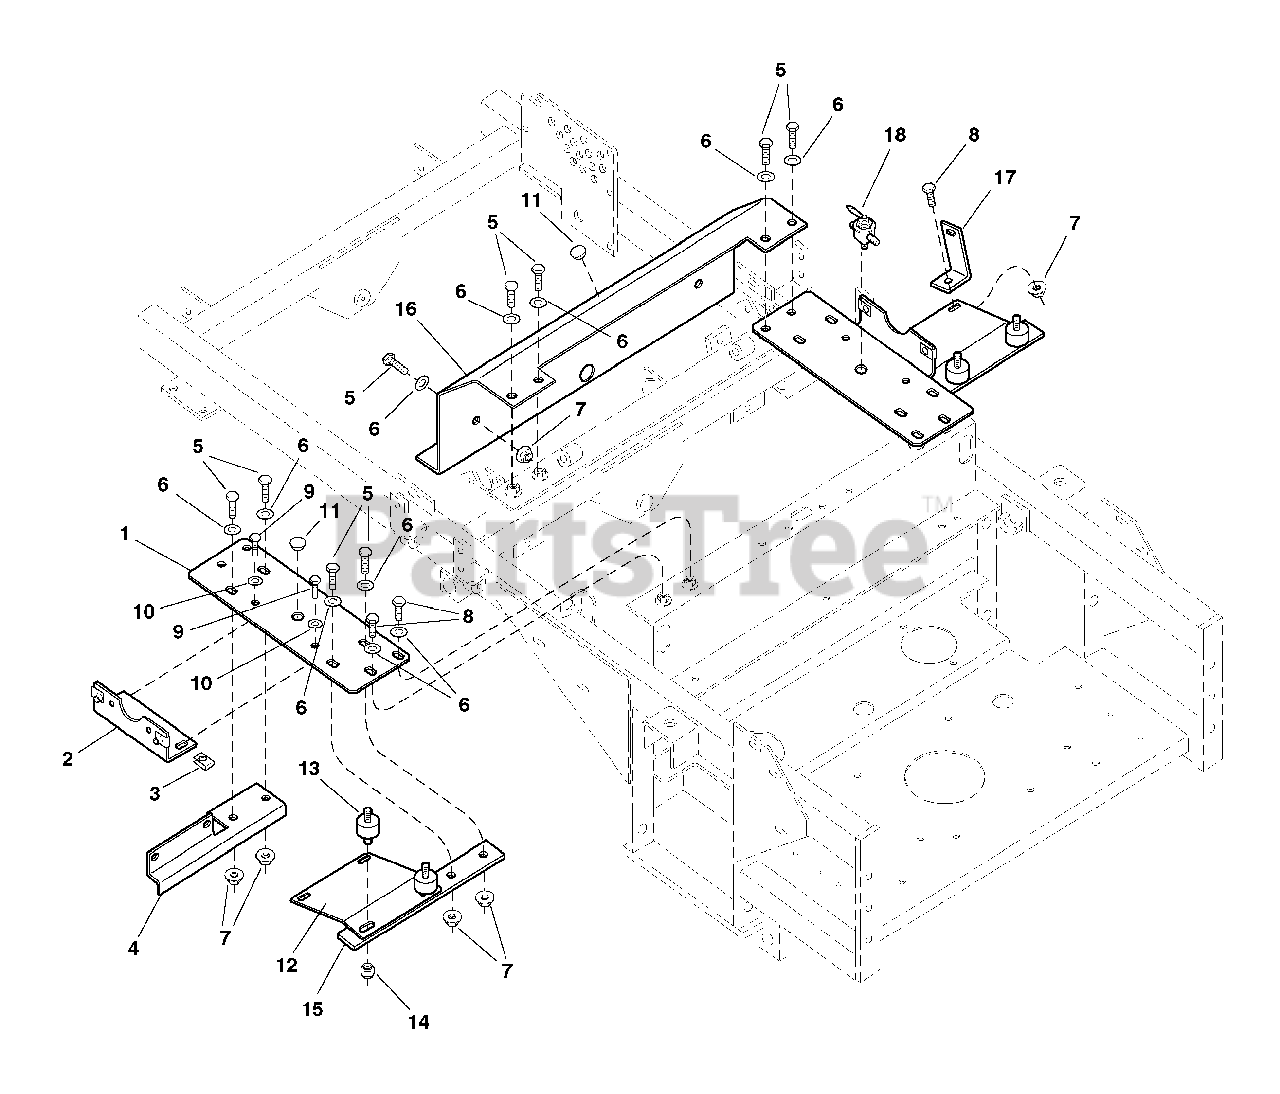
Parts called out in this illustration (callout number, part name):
1	COVER MOUNT PLATE
2	BRACKET, Cover Mount
3	BODY CLIP, 5/16-18
4	INSTRUMENT PANEL MOUNT
5	CAPSCREW, Hex Hd, 3/8-16 x 1
6	WASHER, 3/8
7	NUT, Hex, Serrated Flange, 3/8-16
8	CAPSCREW, Hex Hd, 3/8-16 x 3/4
9	CAPSCREW, Hex Hd, 5/16-18 x 1
10	WASHER, 5/16
12	DEBRIS GUARD
13	RUBBER ISOLATOR
14	NUT, Hex, Serrated Flange, 5/16-18
15	TANK MOUNT BAR
16	BRAKE COVER PANEL
17	BRACKET, Cover Mount
18	VALVE, Fuel Shut Off
